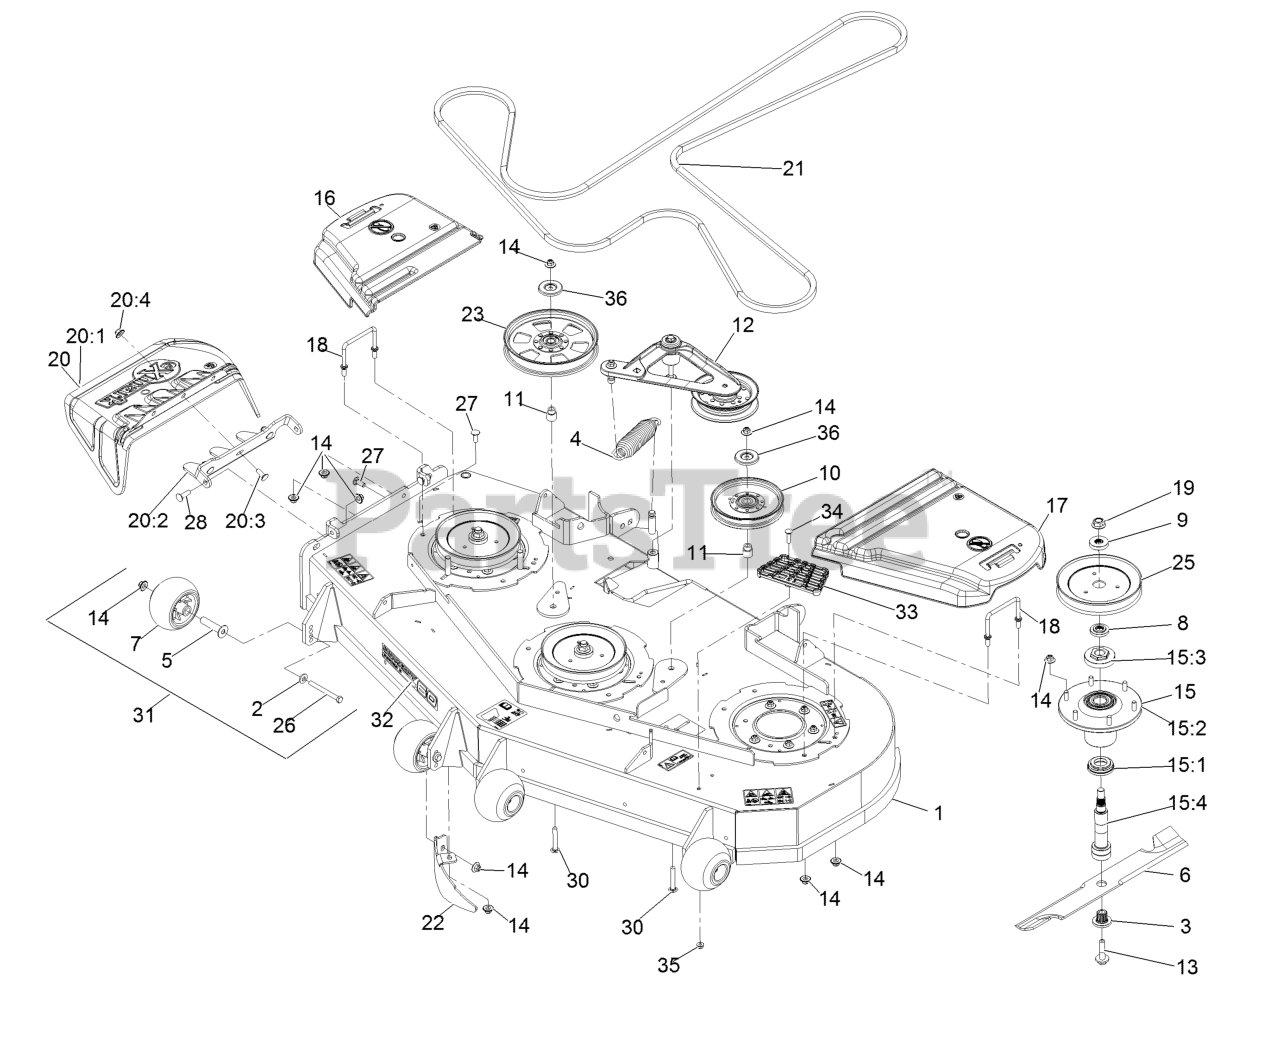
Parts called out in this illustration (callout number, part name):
1	Deck ASM,W/Decals 60
2	Washer-Spring Disc 3/8
3	Bushing, Splined
4	Spring-Extension
5	Axle, Roller
6	Blade, Solid
6	Blade, Low Lift
6	Blade, Mulching
6	Blade, Notched
6	Blade-Extreme 2, 20.50"
7	Roller-Anti-Scalp
8	Spacer, Splined Stepped
9	Spacer, Splined
10	Idler-Pulley
11	Bushing, Idler
12	Deck Idler ASM
13	Screw-Sems 1/2-20 X 2.19
14	Nut-Nyloc 3/8-16 Flg
15	ASM,Spindle Housing
15:1	Guard, Bottom
15:2	Asm, Cutter Housing
15:3	Nut, Spindle 7/8-14
15:4	Spindle,Double Spline
16	Cover-Belt, RH
17	Cover-Belt, LH
18	Wireform-Cover
19	Nut-Flange 5/8-18 Centerlock
20	ASM,Discharge Chute
20:1	Chute, Discharge
20:2	Bracket,Discharge Chute
20:3	Bolt-Carriage 3/8-16 X 1
20:4	Nut-Nyloc 3/8-16 Flg
21	Belt,V-5V-198.75
22	Dogleg - Lz60
23	Pulley-Idler, Flat
25	Sheave,Blade Drive 7.25
26	Screw-HH 3/8-16 X 3 3/4 GR 8
27	Bolt-Carriage 3/8-16 X 1
28	Bolt-Carriage 3/8-16 X 1 1/4
30	Bolt-Carriage 3/8-16 X 2 1/2
31	Kit, Anti-Scalp Roller
32	Decal, 606
33	Step-Deck
34	Bolt-Carriage 5/16-18 X 1 1/4
35	Nut-Nyloc 5/16-18 Flg
36	Shield-Dust
